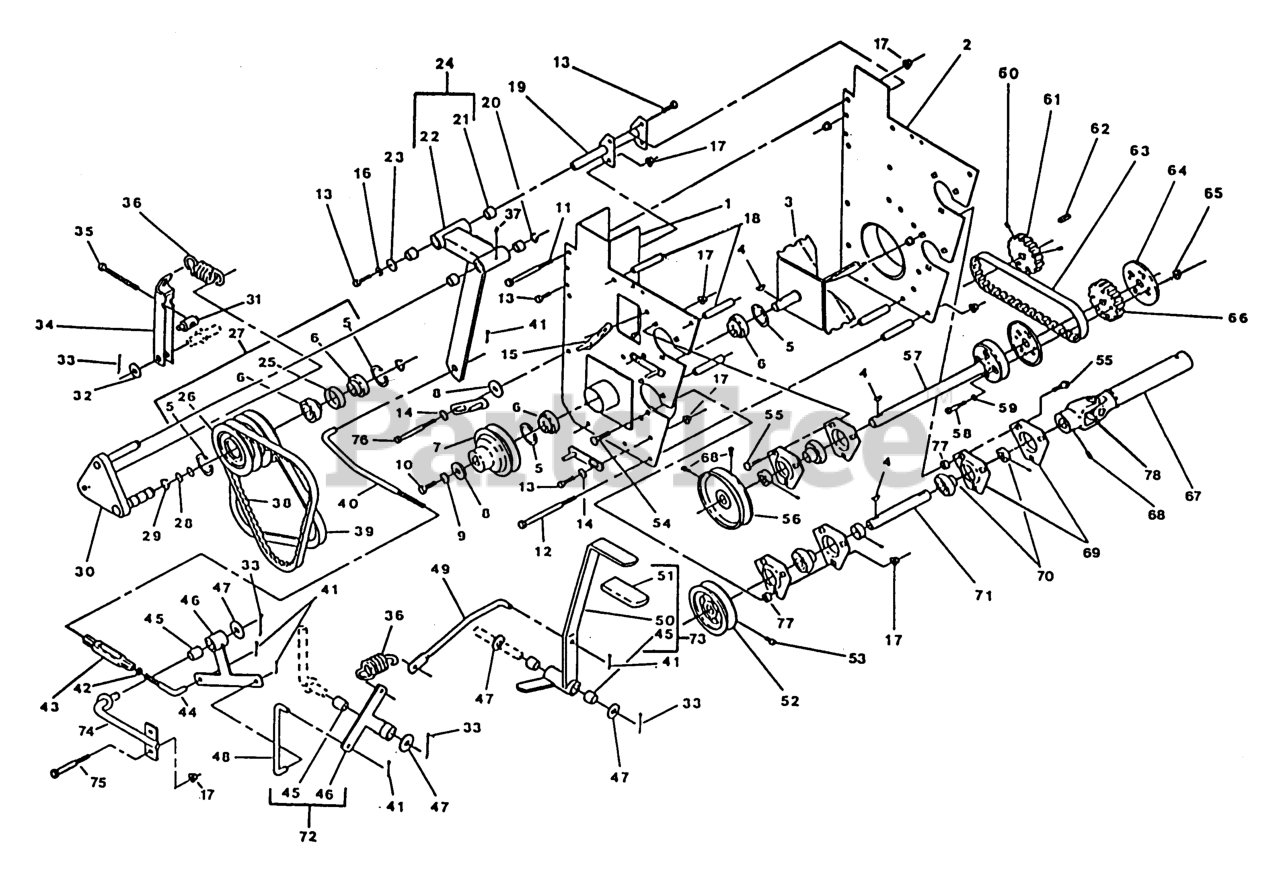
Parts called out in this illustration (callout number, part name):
4	KEY-WOODRUFF
6	BEARING
12	SCREW-HH
14	WASHER-SPRING
15	GUIDE-BELT
16	WASHER-LOCK
22	Control, Transfer Sheave
24	CNTRL ASSY,TRANS SHV
25	SPACER,TRANSFER BEARING
28	O-RING,
29	RING,RETNG WLDS 5108-100
31	SWIVEL,BELT TENSION
36	SPRING,BELT TENSION
38	BELT,PRIMARY DRIVE
39	BELT,SECONDARY DRIVE
40	ROD,PTO LOW RH THD
44	ROD,PTO RH LOW LH THD
45	SLEEVE-BEARING
49	ROD,PTO UPPER
51	GRIP-LEVER
52	SHEAVE,5.5 B
53	SCREW-SET
59	WASHER-LOCK
63	BELT,DRIVE POSITIVE
69	HOUSING-FLANGE
70	BEARING,W/COLLAR
74	WLD,BELLCRANK SUPPORT
